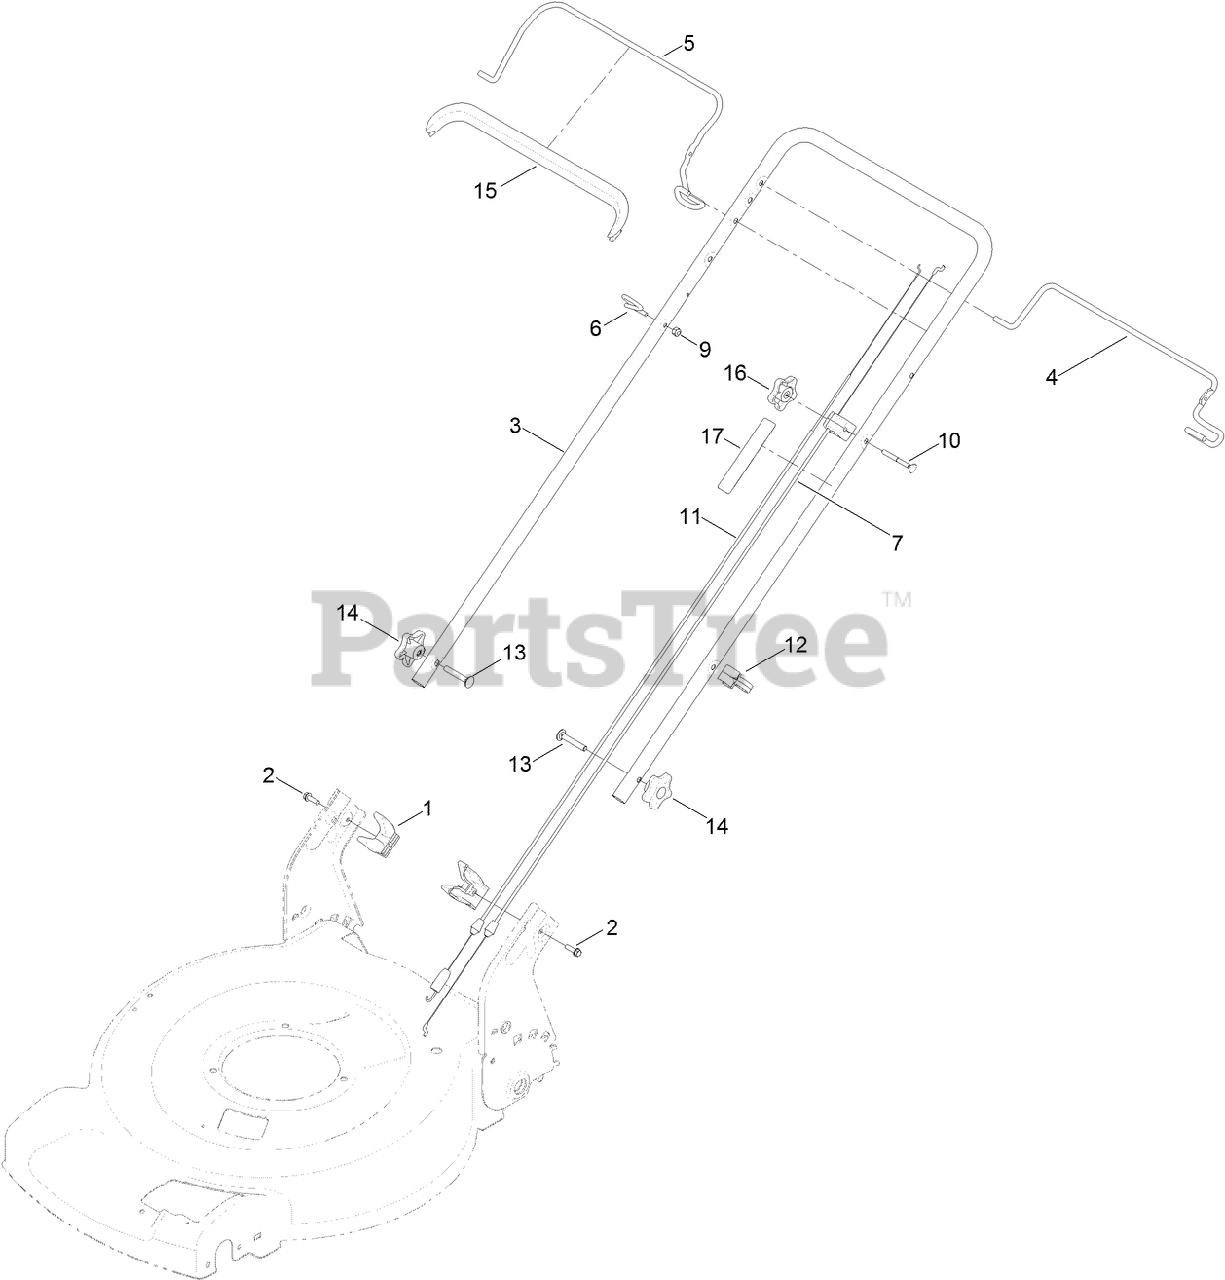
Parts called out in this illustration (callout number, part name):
1	ANCHOR-BAG
2	SCREW-HWH
4	BAIL-TRACTION
5	BAIL-BRAKE
6	GUIDE-ROPE
7	CABLE-BRAKE
9	NUT-LOCK, NI
10	SCREW-HANDLE
11	CABLE-TRACTION
12	GUIDE-CABLE
13	BOLT-CARR
14	KNOB-HANDLE
15	COVER-BAIL
16	KNOB-HANDLE, LOCKING
